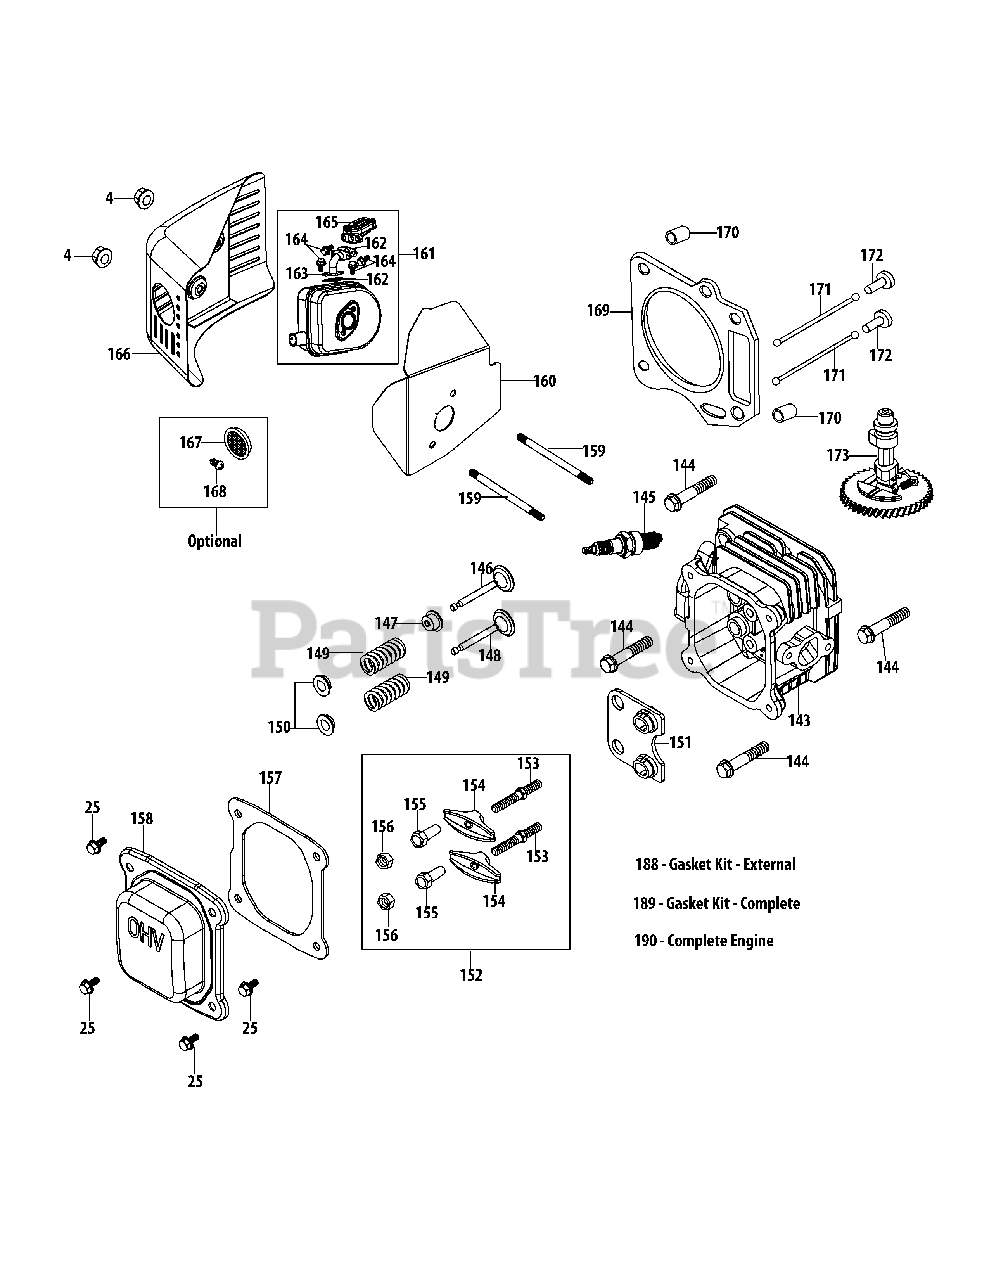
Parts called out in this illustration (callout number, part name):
4	Nut M6X10Mm
25	Bolt M6X14
143	Cylinder Head Service Kit
143	Cylinder Head Assembly
144	Bolt M8X54
145	Spark Plug
146	Valve Kit
147	Intake Valve Seal
148	Valve Kit
149	Valve Spring
150	Valve Spring Retainer
151	Push Rod Guide
152	Rocker Arm Assembly
153	Rocker Arm Stud
154	Rocker Arm
155	Fulcrum Nut
156	Jam Nut
157	Valve Cover Gasket
158	Valve Cover
159	Muffler Stud M6X95
159	Muffler Stud Ass'Y
160	Muffler Gasket
161	Muffler Assembly
162	Secondary Air Valve Gasket
163	Secondary Air Tube
164	Bolt M6×12 Secondary Air Tube/Valve
165	Secondary Air Valve
166	Muffler Shield
167	Spark Arrestor
168	Spark Arrestor Screw
169	Cylinder Head Gasket
170	Cylinder Head Dowel Pin 10×16
171	Push Rod Kit
172	Tappet
173	Camshaft Assembly
188	Gasket Kit - External
189	Gasket Kit - Complete
190	Complete Engine
